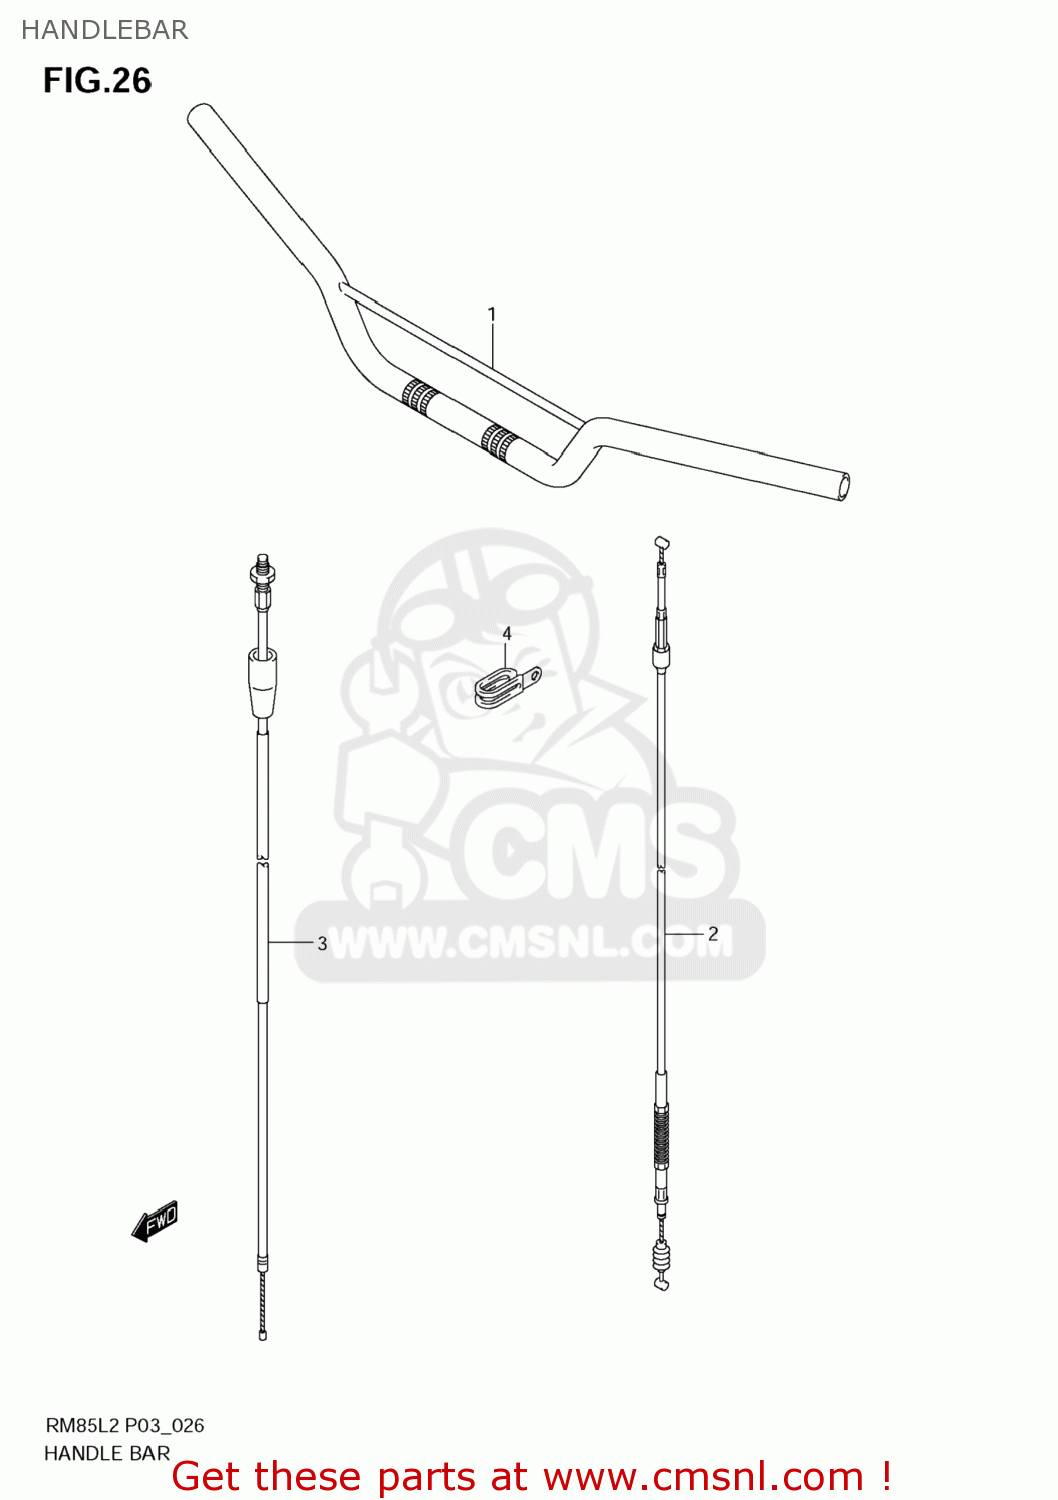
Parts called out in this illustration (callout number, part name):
1	HANDLEBAR COMP
2	CABLE ASSY,CLUTCH
3	CABLE ASSY,THROTTLE
4	CLAMP
